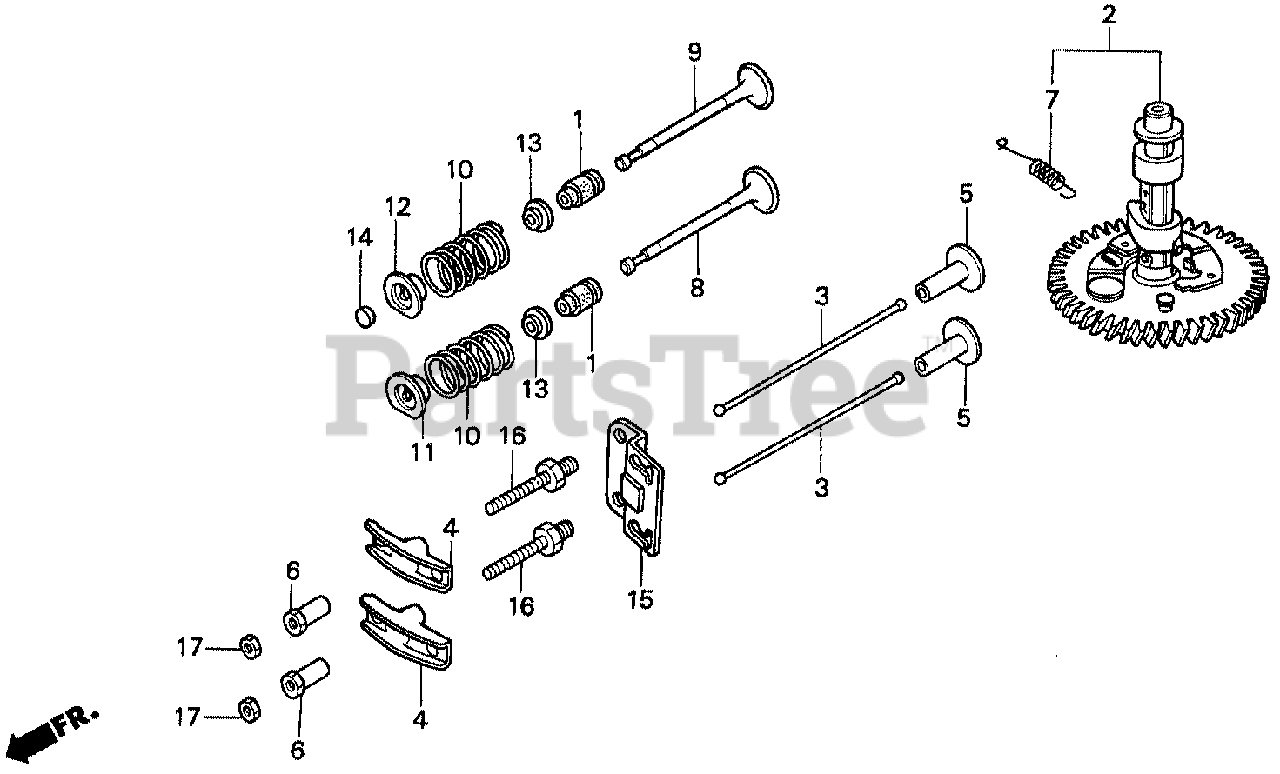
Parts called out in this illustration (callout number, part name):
1	SEAL, VALVE STEM
2	CAMSHAFT ASSY.
2	CAMSHAFT ASSY. (Honda Code 2461721). (NOT AVAILABLE)
3	ROD, PUSH
4	ARM, VALVE ROCKER
5	LIFTER, VALVE
6	PIVOT, ROCKER ARM
7	SPRING, WEIGHT RETURN
8	VALVE, IN.
9	VALVE, EX.
10	SPRING, VALVE
11	RETAINER, IN. VALVE SPRING
12	RETAINER, EX. VALVE SPRING
13	SEAT, VALVE SPRING
14	ROTATOR, VALVE
15	GUIDE, PUSH ROD
16	BOLT, PIVOT (8MM)
17	NUT, PIVOT ADJ.
